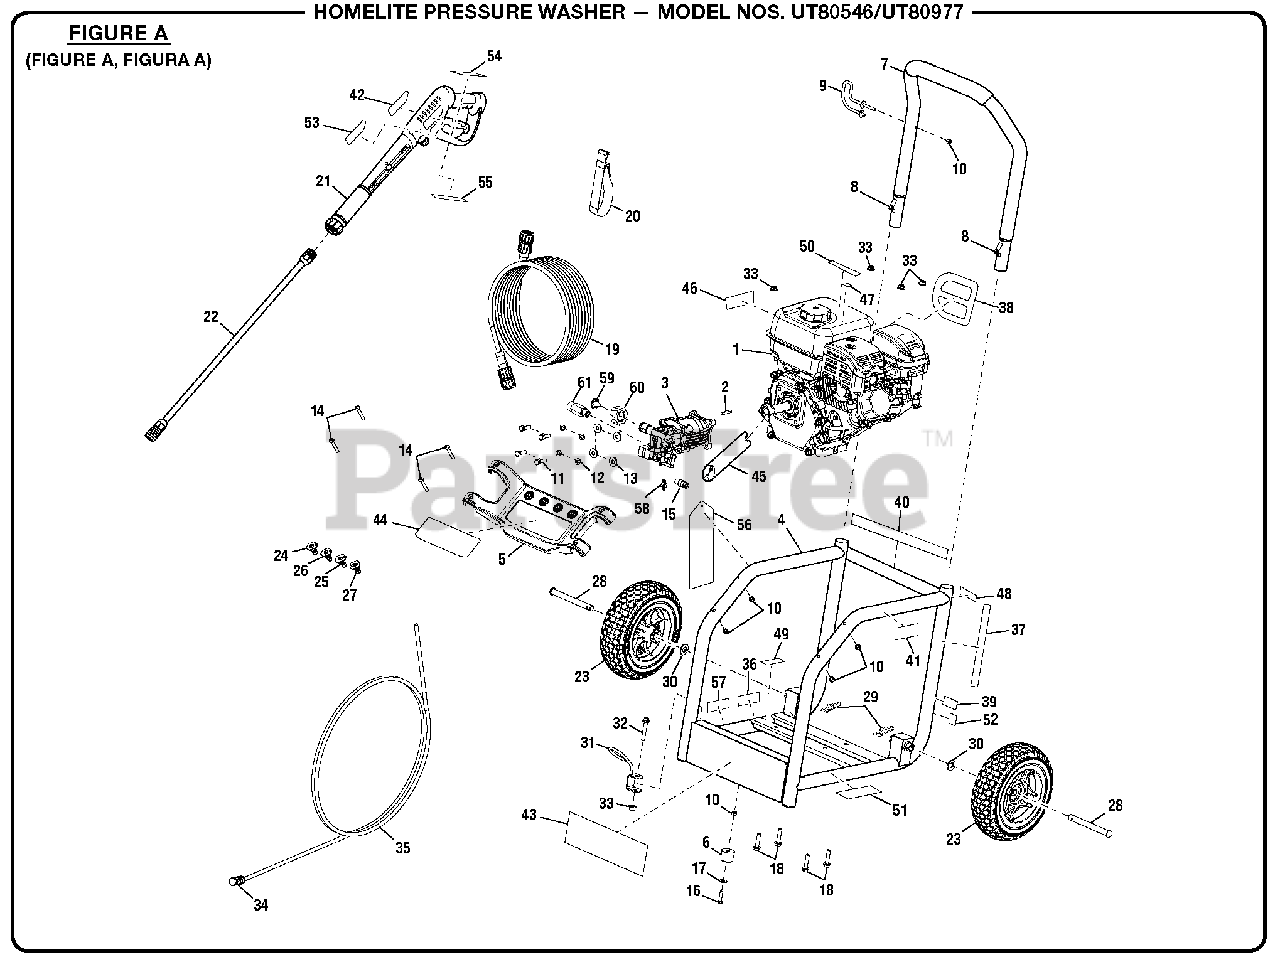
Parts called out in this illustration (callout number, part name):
1	Engine
2	Output Shaft Key (3/16 x 35 mm)
4	Main Frame
5	Nozzle Holder
6	Rubber Foot
7	Handle Assembly
8	Lock Button w/Spring Clip
9	Wand Holder (Upper)
10	Lock Nut (1/4-20)
11	Bolt (5/16-24 x 27 mm, Hex Hd.)
12	Lock Washer (5/16 in.)
13	Washer (5/16 in.)
14	Screw (1/4-20 x 2.0 in., Torx)
15	Thermal Release Valve
16	Bolt (1/4-20 x 1-1/4 in.)
17	Washer (1/4 in.)
18	Bolt (M8 x 40 mm, Hex Flange Hd.)
20	Hook and Loop Strap
21	Trigger Handle
22	Extension Wand
23	Wheel Assembly (10 in. x 3 in.)
24	Nozzle, 0º
25	Nozzle 40º
26	Nozzle 25º
27	Soap Nozzle
29	Hitch Pin
30	Washer (1/2 in.)
31	Wand Holder (Lower)
32	Bolt (M8 x 50 mm, Flange Hd.)
33	Lock Nut (M8 x 1.25)
35	Chemical Siphon Tube
36	Pump Start Label
37	Engine Start Label
38	Recoil Label
39	Choke Label
40	Data Label
41	Hot Surface Label
42	Trigger Handle Logo Label
43	Homelite Label
44	Performance Label
45	Add Oil Label
46	Danger Label
47	E85 Label
48	Homelite Inquiries Label
49	Dip Stick Label
50	No Oil To Gas Label
51	Combustion Label
52	Fuel Label
53	Trigger Handle Warning Label (French and Spanish)
54	Warning Label English)
55	Wand Label (Max Rating)
56	Danger Hangtag
57	Lubricant Label
58	Detergent Suction Kit
59	Filter Screen
60	Inlet Tube
61	Outlet Tube
